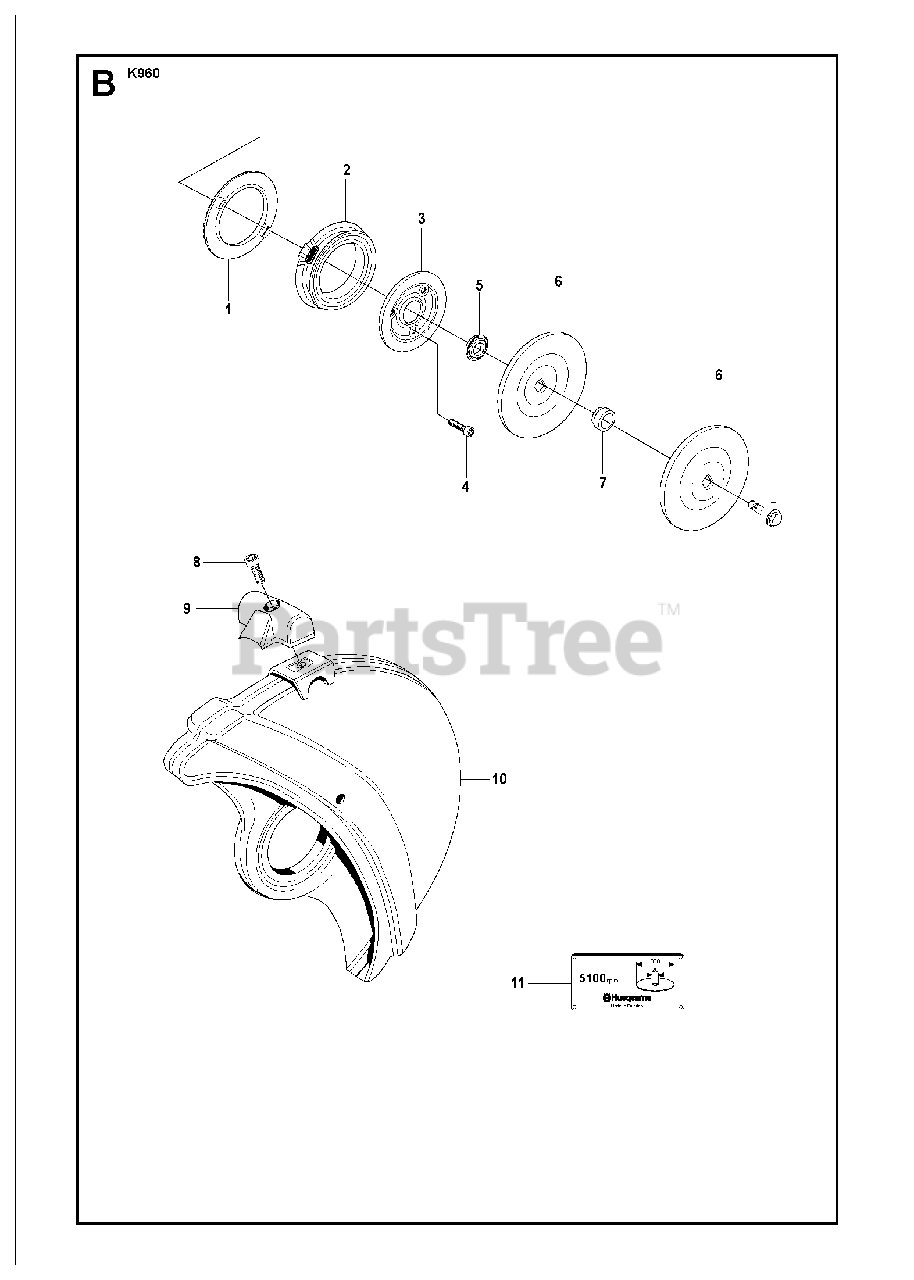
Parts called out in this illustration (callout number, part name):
5	SUPPORT FLANGE
6	FLANGE WASHERDiam 105
6	FLANGE WASHERDiam 116
7	KITDiam 22,2
7	BUSHINGDiam 30,5
8	SCREW IHSCM
10	WHEEL GUARD"12"". Incl. 2, 9, 10"
10	WHEEL GUARD"14"". Incl. 2, 9, 10"
10	GUARD"16"". Incl. 2, 9, 10"
11	LABEL"12"". Diam 1"""
11	LABEL"12"". Diam 20 mm"
11	LABEL"14"". Diam 1"""
11	LABEL"14"". Diam 20 mm"
11	LABEL"16"". Diam 1"""
11	LABEL"16"". Diam 20 mm"
